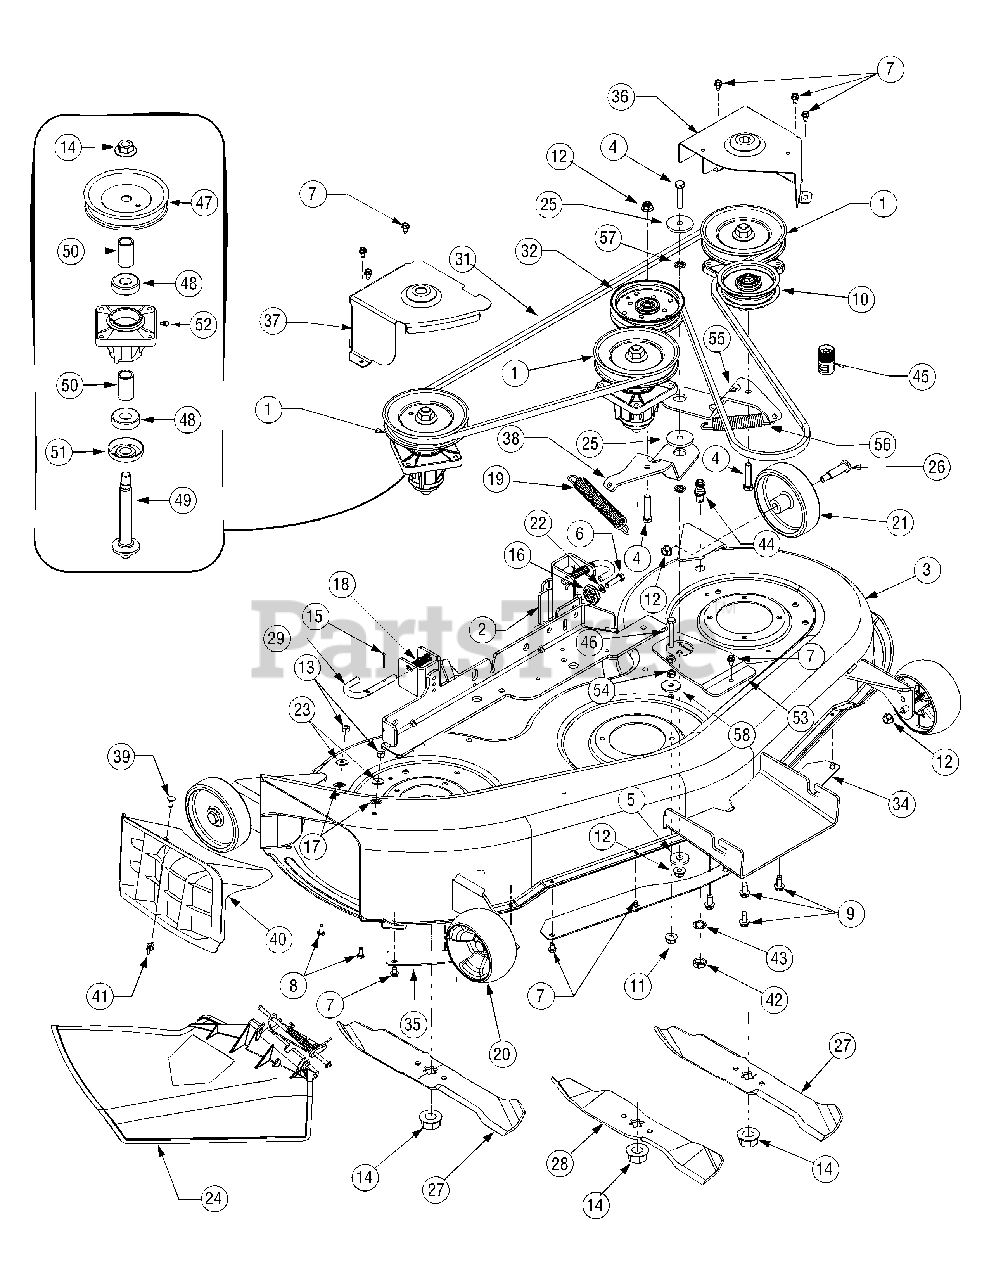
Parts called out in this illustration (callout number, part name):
1	Spindle Assembly
4	Screw, 3/8-16, 1.75
5	Washer, Flat, .450 x 1.25 x .164
6	Screw, 5/16-18, 1.25, Gr5
7	Screw, Hex. Wash, 1/4-20, 0.5
8	Screw, Hex Cap, 1/4-20, .750, Gr5
9	Self-tapping Screw, 5/16-18 x .75
10	Pulley, Idler, 3.5"
11	Nut, Nylon Lock, 5/16-18
12	Nut, Nylon Lock, 3/8-16
15	Cotter Pin, 1.0
16	Deck Adjustment Gear
18	Compression Spring, 1.75
19	Extension Spring, 7.33
20	Deck Wheel, 5.0
21	PLASTIC WHEEL 5X1.38
22	Washer, Lock, 5/16, Regular Duty
23	SPRING WASHER BELL
24	Chute Assembly, Side Discharge
25	Spacer, Shoulder, .884 x .190
26	Shoulder Screw
27	Blade, 16.28
28	Blade, 14.88
29	Rod, Handle, Deck Release
31	Belt, V-Type
32	Idler Pulley, 4.25"
40	Mulch Plug
41	WING NUT 1/4-20
42	Nut, Hex, M16-1.5
43	Washer, Lock, Internal Tooth
44	Port, Water
45	Coupler, Hose
46	Hex Screw, 5/16-18 x 2.0
47	Pulley, 5.75 Dia.
48	Ball Bearing, .787 x 1.85 x .551
49	Shaft, Spindle, 6.11 Lg
50	Spacer, 1.8
51	Bearing Shield
52	GREASE FITTING
53	Support Bracket, Idler
54	HEX NUT 5/16-18
57	Push Nut, 3/8
58	Washer, Flat, .330 x 1.25 x .120
